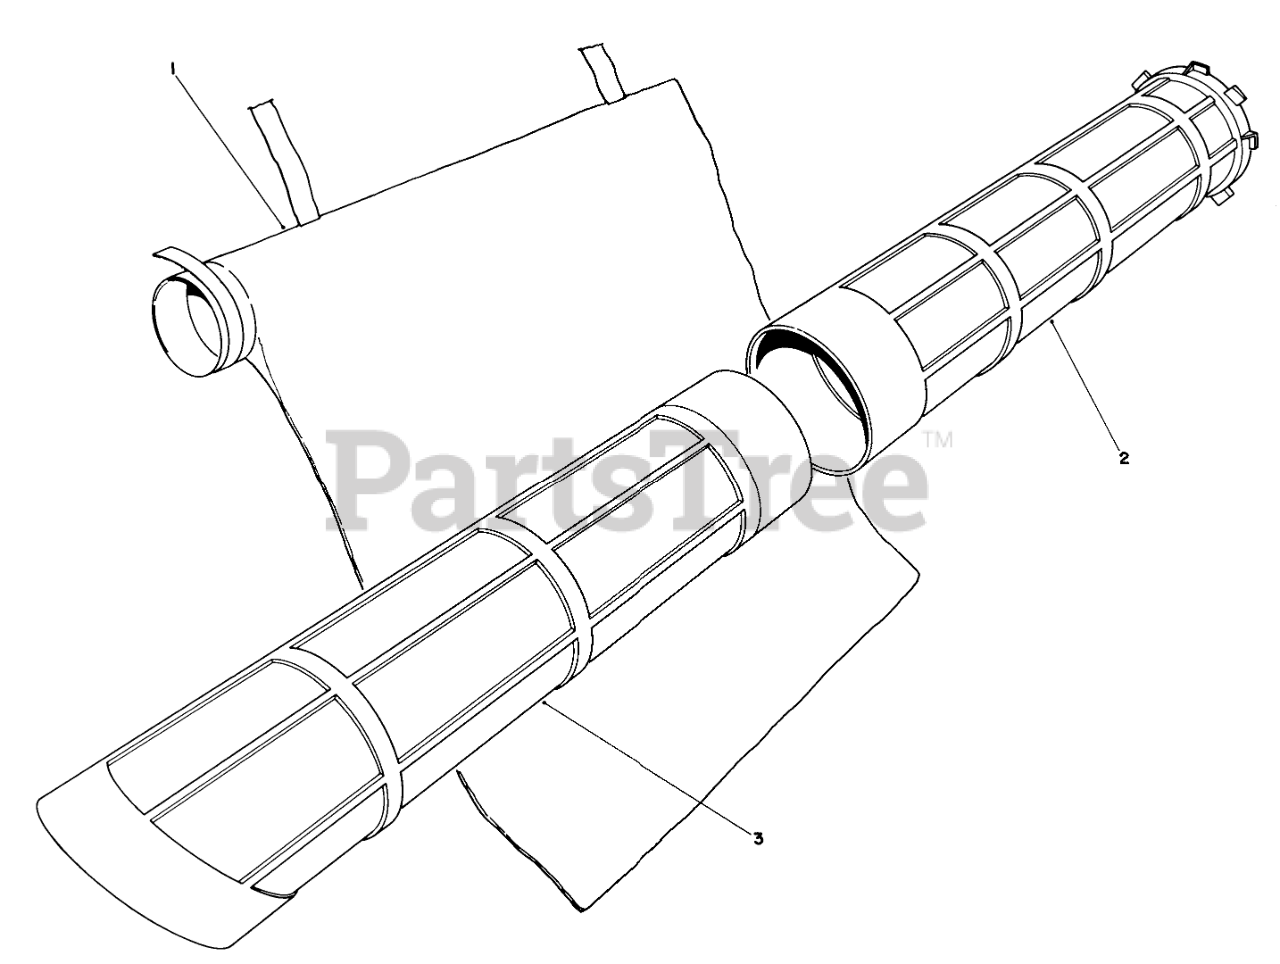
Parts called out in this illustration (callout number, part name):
1	VACUUM BAG
2	Tube-Upper Vacuum
3	Tube-Lower Vacuum
